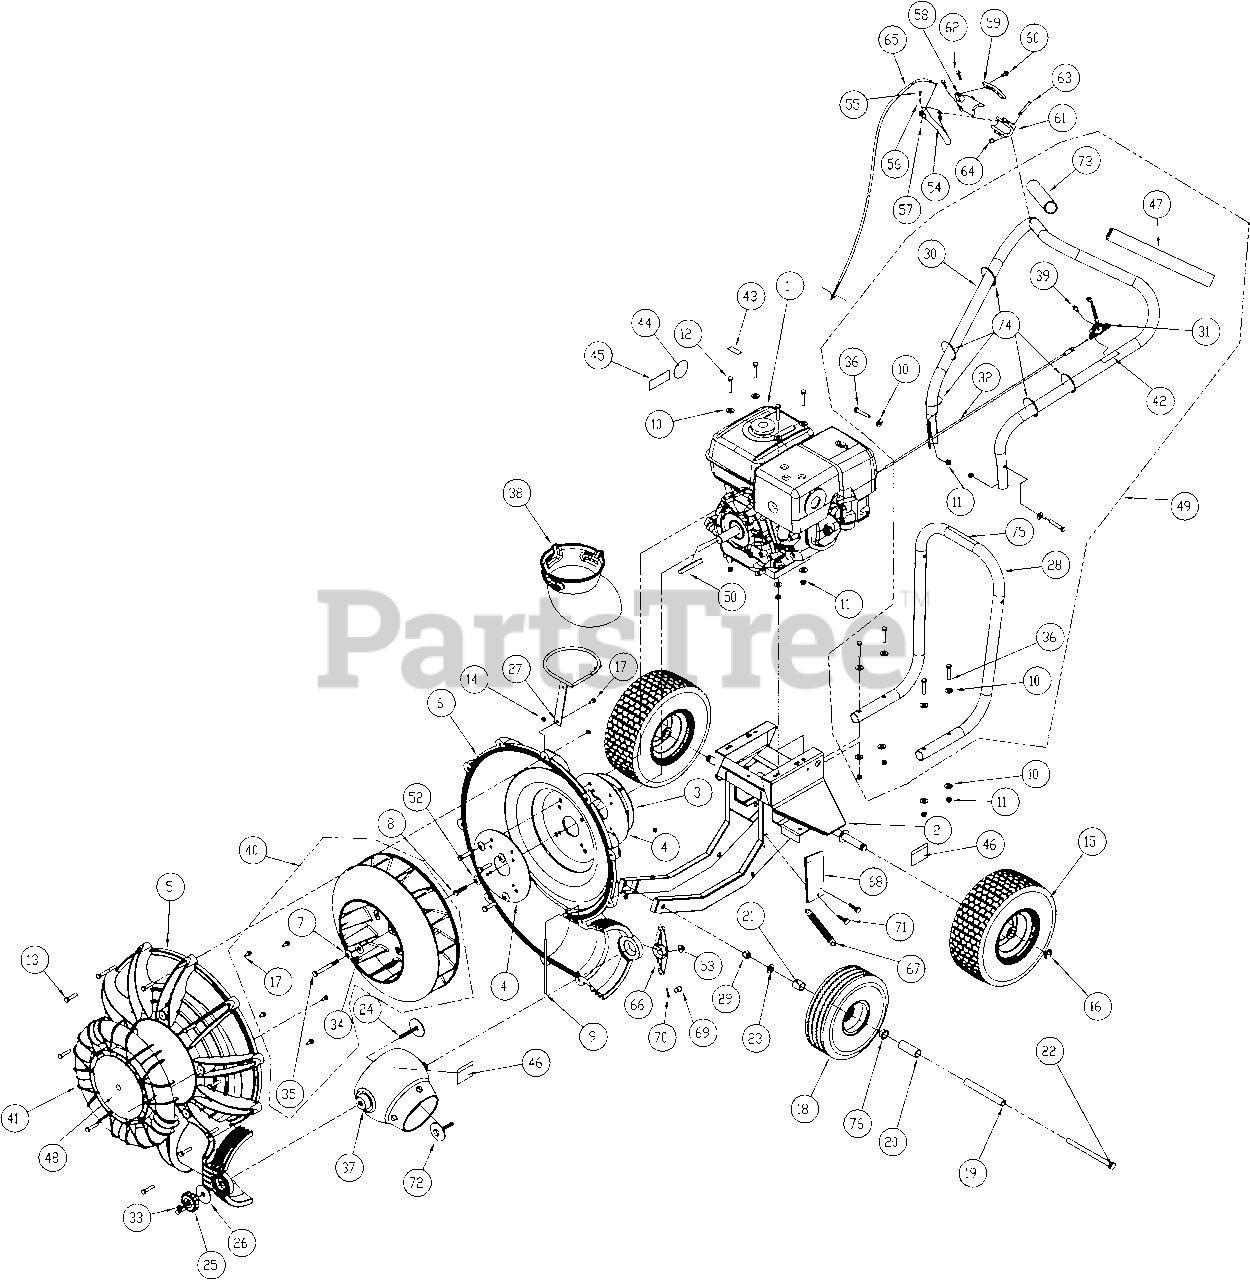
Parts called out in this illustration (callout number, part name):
1	ENGINE 9 HP HONDA GX270
1	ENGINE 9 HP HORZ SUBARU OHC
2	BASE ENGINE WA
3	SPACER RING ENGINE
4	PLATE REINFORCE HOUSING
5	HOUSING FRONT MOLDED
6	HOUSING BACK MOLDED
7	WASHER LOCK
8	SCREW CAP 3/8-16X1 1/2 ZP
9	ROD HAND STOP
10	WASHER 5/16 FLATWASHER Z/P
11	NYLON INSERT LOCKNUT 5/16-18
12	SCREWCAP 5/16-18 X 1.75 ZP
13	SCREWCAP 1/4-20 x 1 1/2
14	NUT FLANGE 1/4-20
15	WHEEL & TIRE 13" X 5" PNEUMATIC
16	RING RETAINING 3/4
17	SCREW SELF-TAP 5/16 NC X 3/4 HEX
18	WHEEL ASSY 10 " PNEUMATIC
19	SPACER FRONT AXLE
20	SPACER LH WHEEL
21	SPACER RH WHEEL
22	SCREWCAP 1/2-13 x 7"
23	WASHER FLAT 1/2" SAE
24	WASHER W/BOLT WA
25	KNOB 3/8-16 SOLID HUB
26	WASHER 2.25 OD x .515 ID x .134 ZP
27	BRACKET HOLDER WA
28	HANDLE LOWER
29	NYLON INSERT LOCKNUT 1/2-13
30	HANDLE UPPER
31	CONTROL THROTTLE
32	CABLE THROTTLE CONTROL
33	NUT LOCK 3/8-16 LT WT THIN ZP
34	WASHER 1.5 O.D.X 0.45 I.D. X 0.5
35	SCREWCAP 7/16-20 X 3.5 GR.8 55-60ft-lbs
36	SCREWCAP 5/16"-18 X 2" ZP
37	DIRECTOR CONE 4"
38	DIVERTOR FRONT
39	SCREW SM #10-24X1/2" DRILL POINT
40	IMPELLER ASSEMBLY 17"
41	GRILL FRONT BLOWER
42	LABEL THROTTLE CONTROL
43	LABEL HOT ENGINE
44	LABEL READ
45	LABEL EAR EYE BREATHING
46	LABEL DANGER FLYING DEBRIS
47	GRIP 1-1/4" ID x 13"
48	LABEL FORCE
49	HANDLE ASSY UPPER
50	Key 1/4" SQ x 2.25
52	WASHER LOCK 3/8 S/T MED
53	NUT LOCK 1/4"-20 HEX ZP
54	HANDLE DIVERTER FORCE
55	PIN LATCH DIVERTER
56	SPRING COMPRESSION 0.281 X 0.88
57	RING RETAINING .122 DIA
58	SADDLE UPPER DIVERTER
59	PLATE LOCK DIVERTER
60	SCREW PLASTITE #6-19 X 5/8"
61	SADDLE LOWER DIVERTER
62	SCREW PLASTITE #10-14 X 1"
63	PIN PIVOT DIVERTER CONTROL
64	RING RETAINING 5/16
65	CABLE ASSY
66	DIVERTER PIVOT ADAPTOR
67	SPRING EXTENSION 0.468 X 5.25
68	BRACKET DIVERTER FORCE
69	PIN CLEVIS 1/4 X 3/4
70	.051 X 3/4" HITCH PIN CLIP
71	SCREW TCS #12-24 X 5/8 TYPE
72	ADAPTOR MOUNT WA
73	GRIP 1-1/4" ID x 9.5" LONG
75	VIBRATION LABEL
76	FORCE WHEEL BEARING .751 ID
